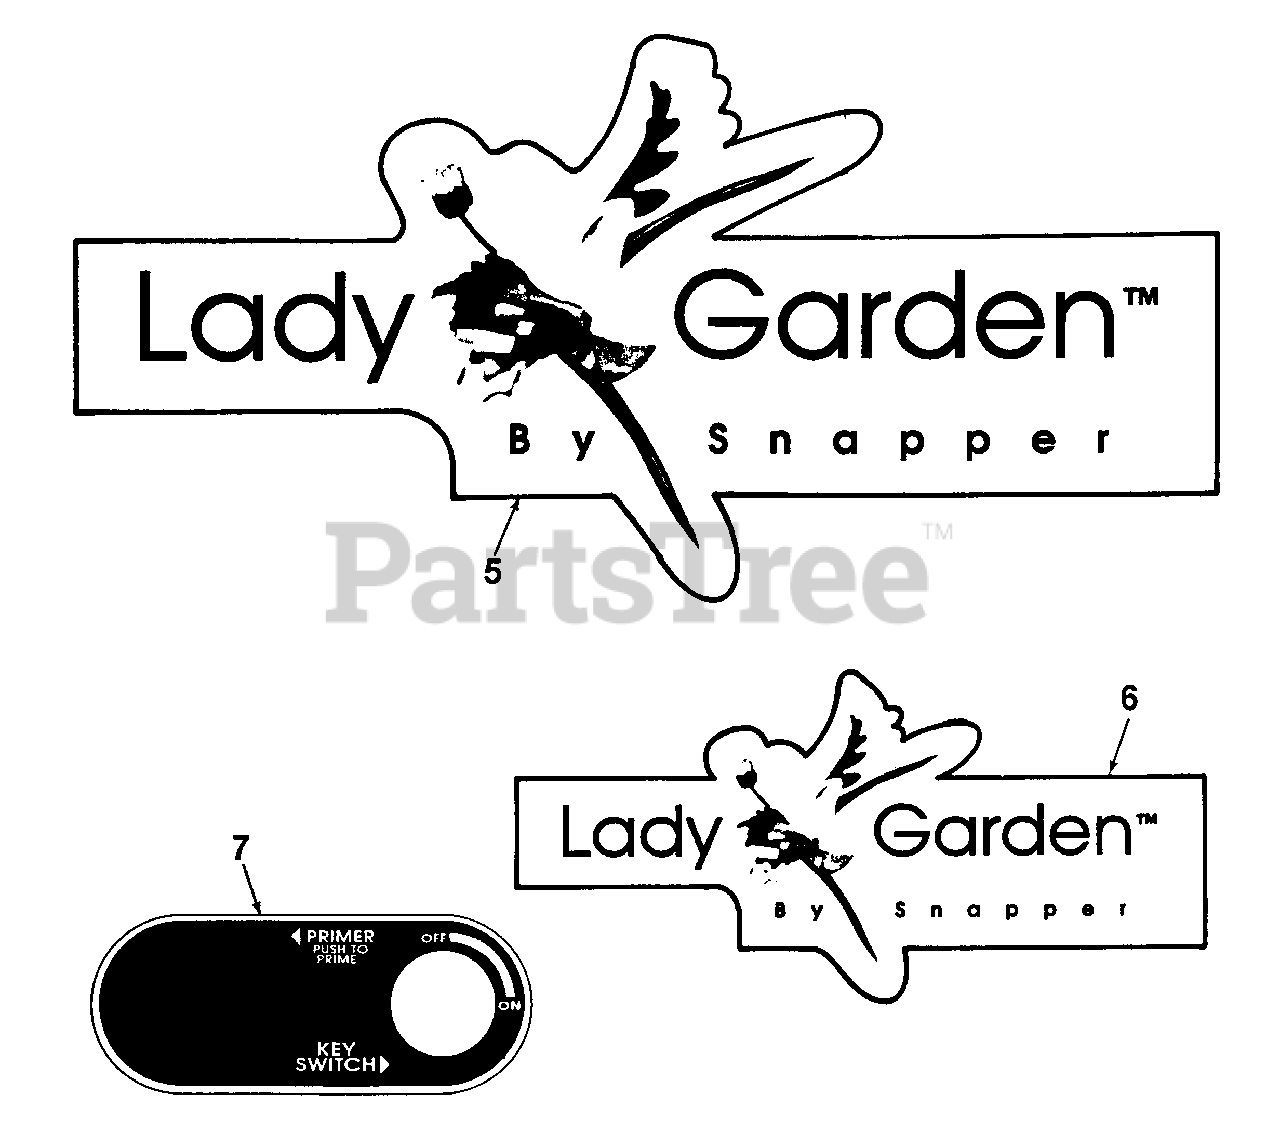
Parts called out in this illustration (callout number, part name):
5	DECAL, Lady Garden Logo (Large)
6	DECAL, Lady Garden Logo (Small)
7	DECAL, Instructions, Primer/Key Switch
